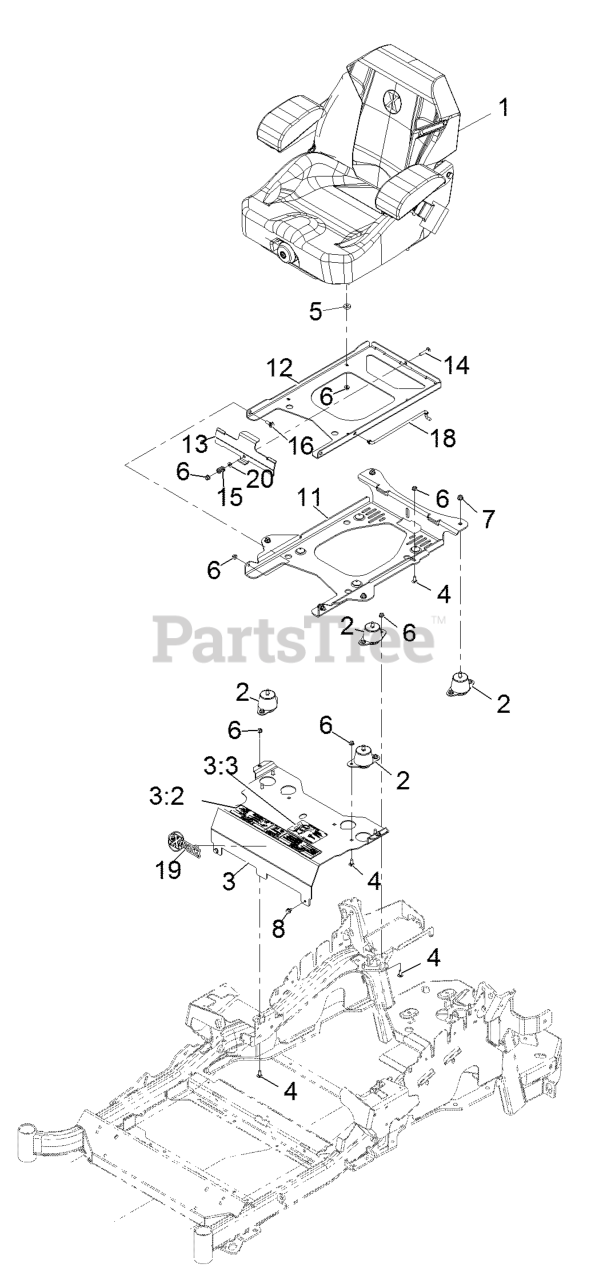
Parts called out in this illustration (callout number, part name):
1	KIT-SUSPENSION SEAT
2	ISOLATOR-SEAT
3	MOUNT-SEAT
3:2	DECAL-CONSOLE
3:3	DECAL-SERVICE AID
4	SCREW-CARR
6	NUT-HF, NI
7	NUT-HF, NI
11	PLATE-TILT, SEAT SUPPORT
12	PLATE-FRAME, SEAT
13	PLATE-LATCH, SEAT
14	BOLT-CARR
15	SPRING-COMPRESSION
16	SCREW-SHOULDER
18	ROD-PROP
20	WASHER-PLAIN
